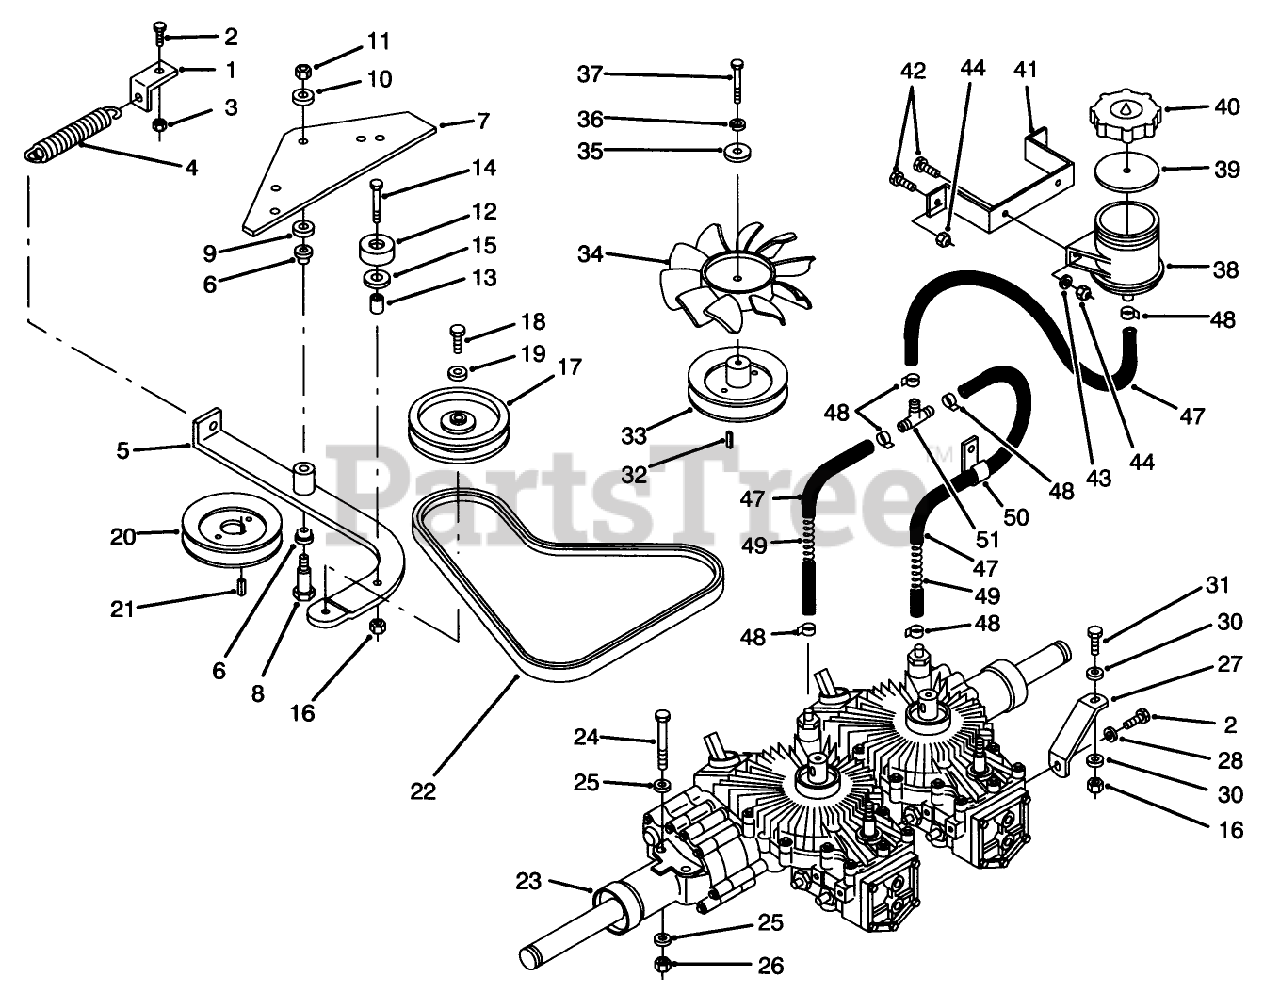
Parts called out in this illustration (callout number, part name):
1	BRACKET-SPRING
2	SCREW-HH
3	NUT-LOCK, NI
4	SPRING-EXTENSION
6	BUSHING
8	BOLT-SHOULDER
9	WASHER
10	WASHER-FLAT
12	BUMPER
13	SPACER
14	SCREW-HH
15	WASHER
16	NUT-LOCK, NI
17	PULLEY IDLER
18	SCREW-HH
19	WASHER-FLAT
22	V-BELT
24	SCREW-HH
25	WASHER-FLAT
26	NUT-LOCK, NI
27	BRKT-HYDRO SIDE
28	WASHER-SPECIAL
30	WASHER-PLAIN
31	SCREW-HH
32	KEY WOODRUFF
34	FAN-7"
35	WASHER
36	WASHER-LOCK
37	SCREW-HH
39	COVER GASKET
42	SCREW-HH
43	WASHER-FLAT
44	NUT-LOCK, NI
47	HOSE-7"
49	COMPRESSION SPRING
50	CLAMP
51	TEE-5/8 PLASTIC
